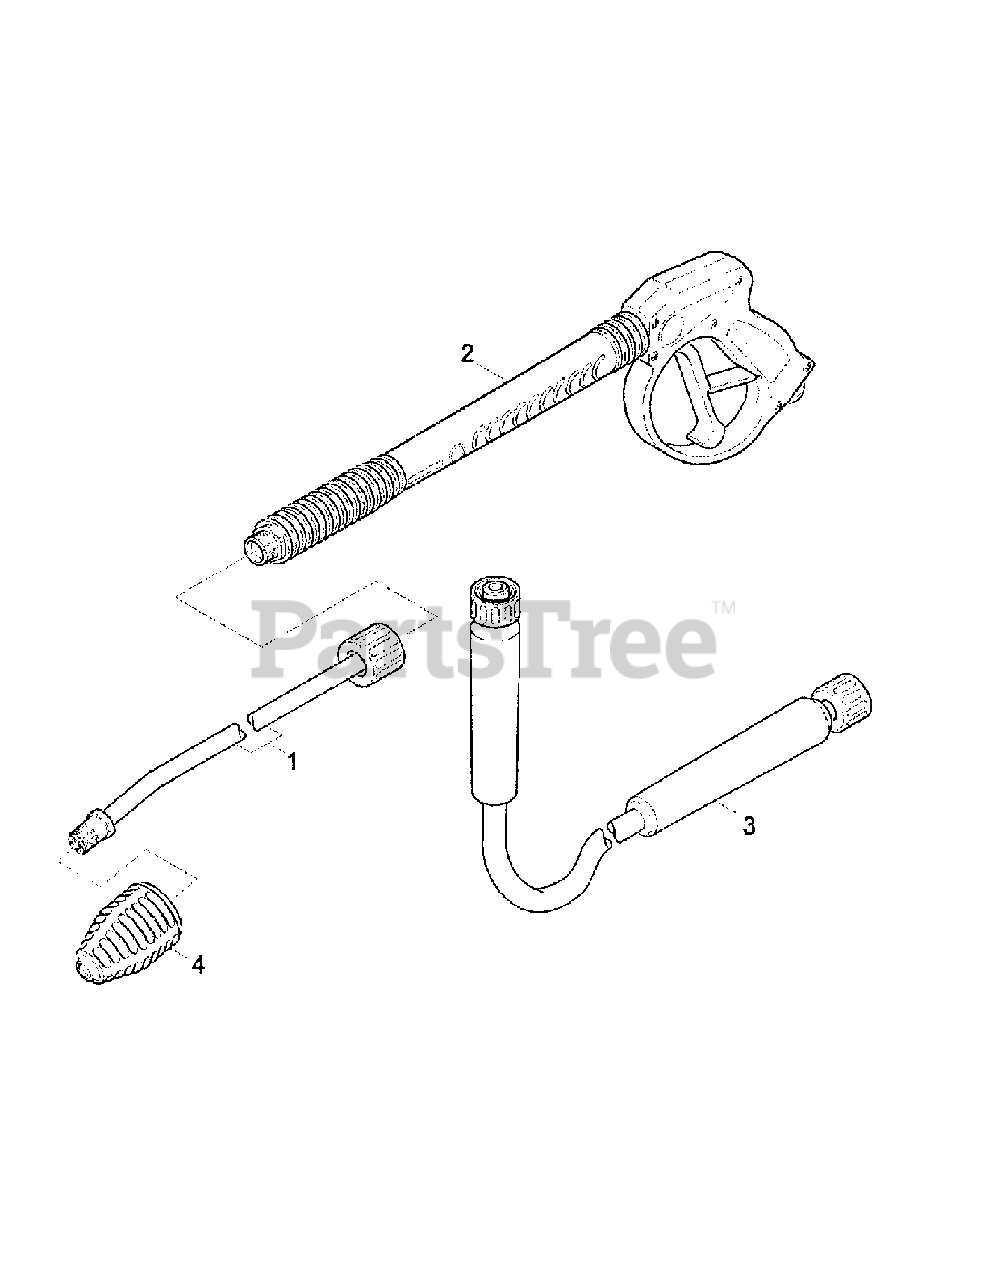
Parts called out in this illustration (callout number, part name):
1	Jet Pipe
2	Trigger Gun
3	High Pressure Hose
4	Rotary Nozzle
